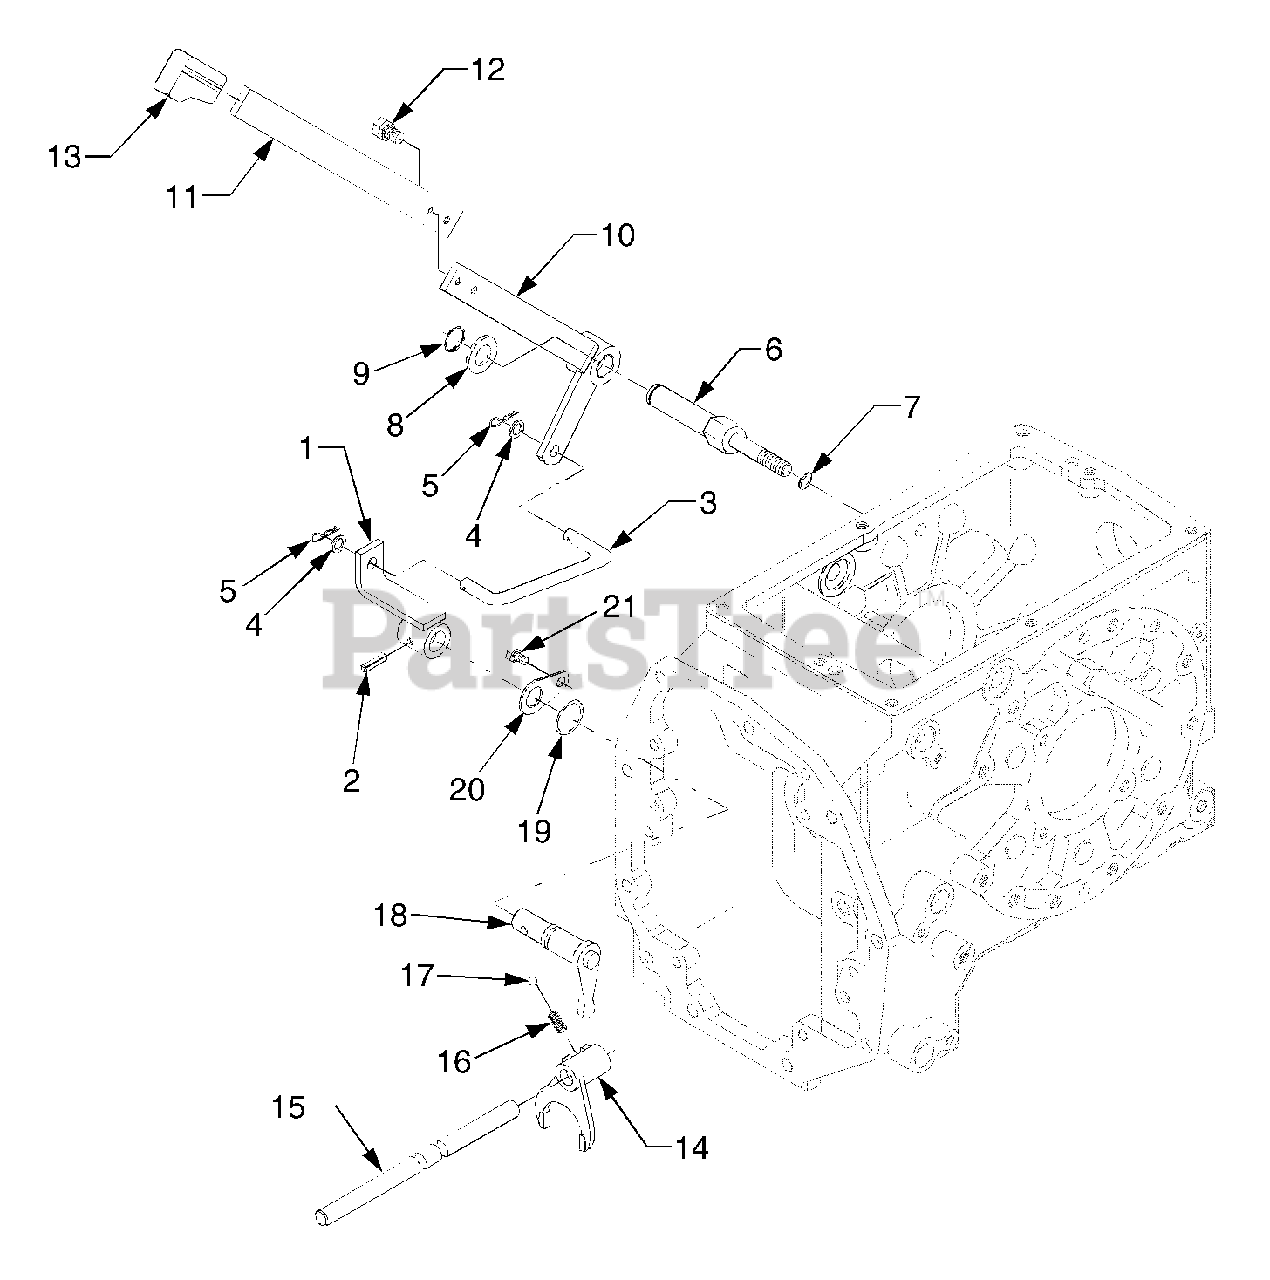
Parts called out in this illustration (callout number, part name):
1	Lever 1, Mid PTO
3	Rod (Mid PTO)
4	Washer, Plain
6	Shaft, Lever (Mid PTO)
7	Washer, Spring
8	Washer, Plain
10	Mid PTO Lever Ass'y
11	Lever, Mid PTO
14	Fork, Shift (Mid)
15	Rod, Fork (Mid)
